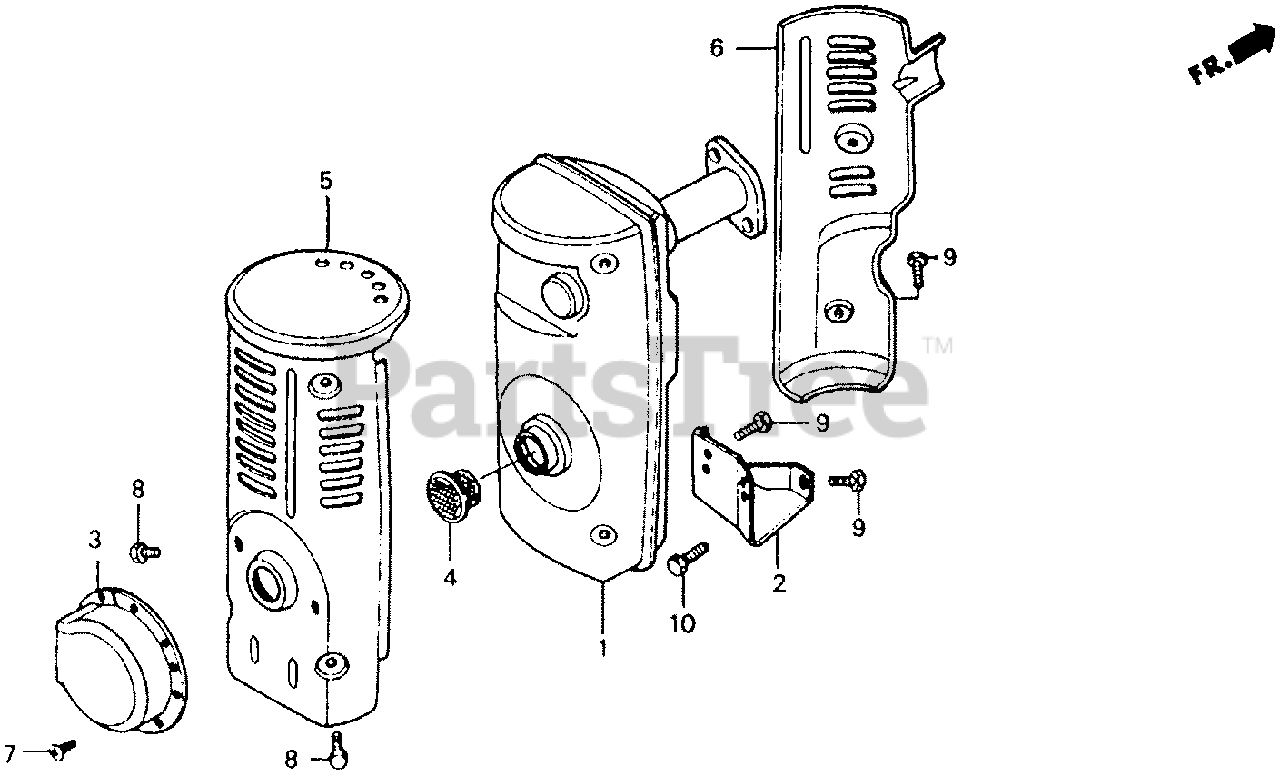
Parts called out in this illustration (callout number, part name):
1	MUFFLER
2	STAY, MUFFLER
3	DEFLECTOR, MUFFLER
4	FLANGE, BAFFLE
5	PROTECTOR A, MUFFLER
6	PROTECTOR B, MUFFLER
7	SCREW, TAPPING (4X8)
8	BOLT-WASHER (6X10)
8	BOLT, HEX. (6X8)
9	BOLT, FLANGE (6X10)
10	BOLT, FLANGE (8X14)
10	BOLT, FLANGE (8X16)
